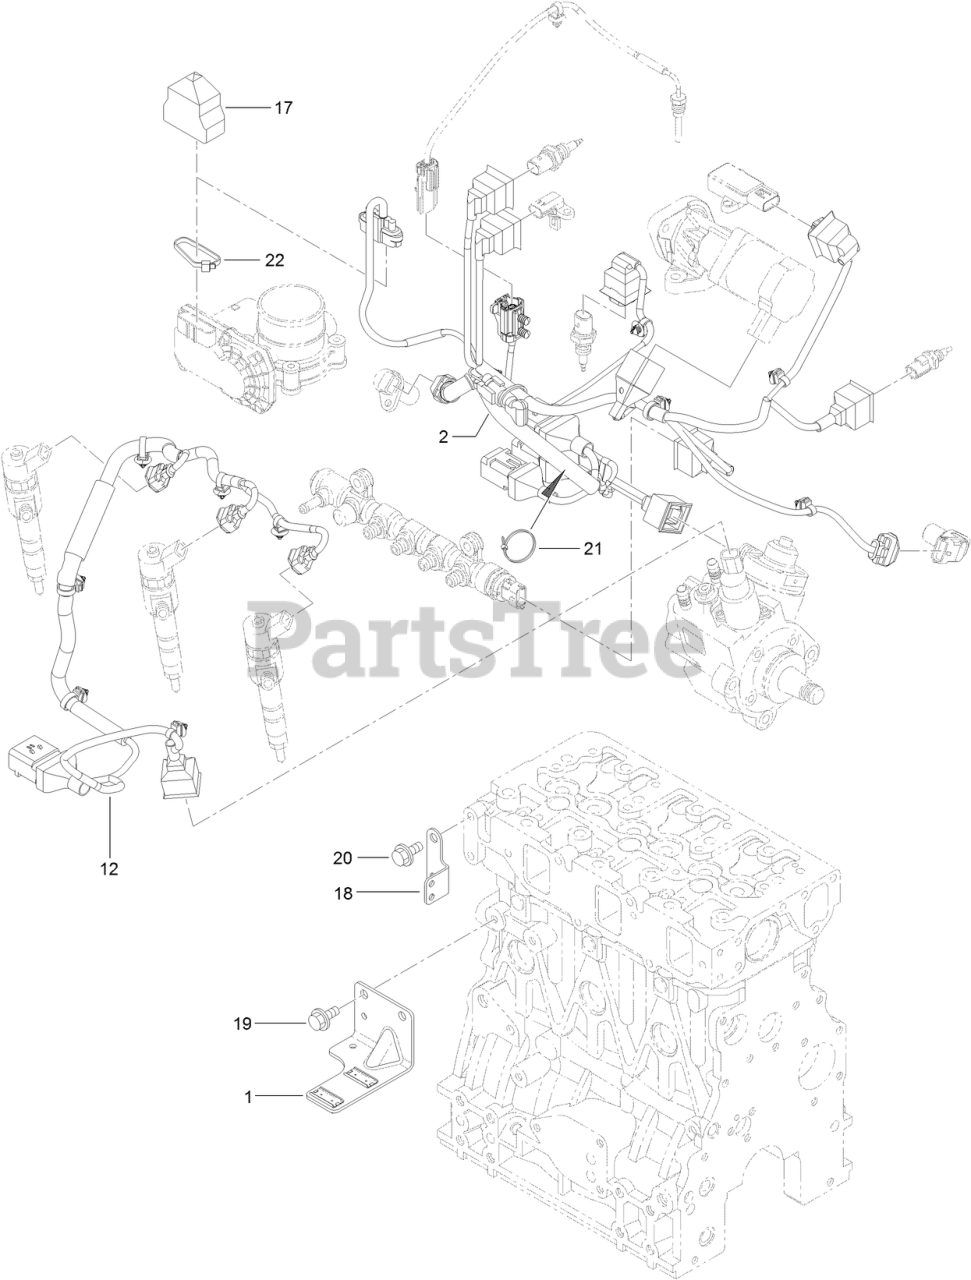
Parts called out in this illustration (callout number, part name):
1	BRACKET-CONNECTOR
2	HARNESS
12	HARNESS
17	BOOT-CAP
18	BRACKET-HARNESS
